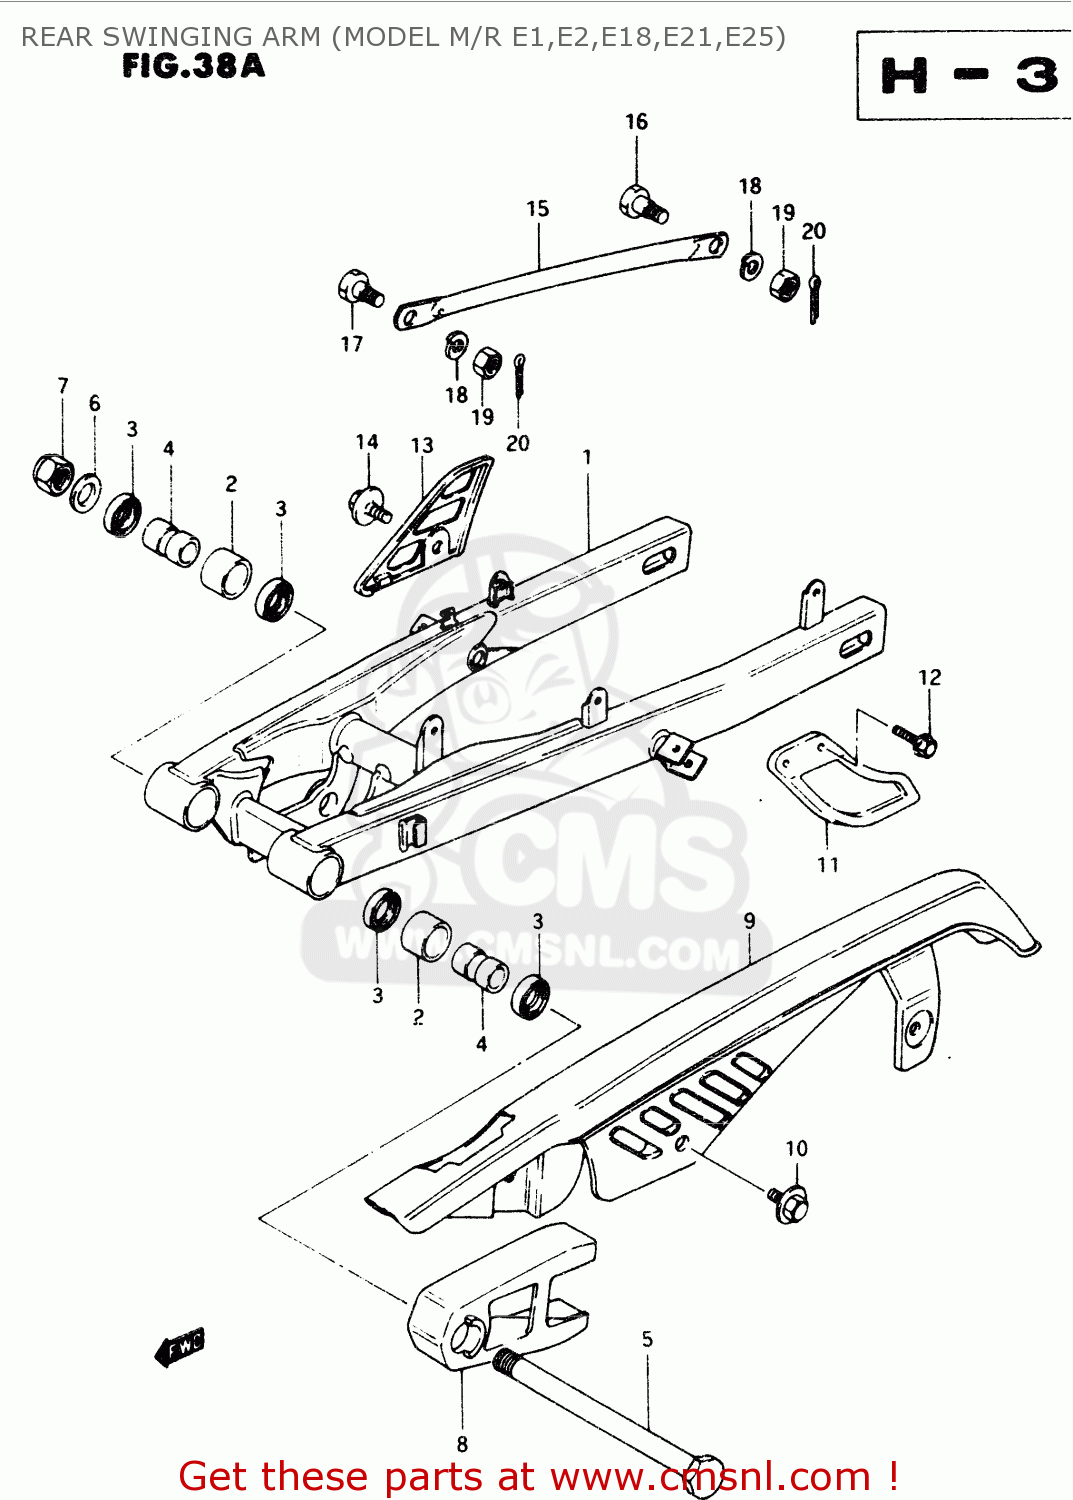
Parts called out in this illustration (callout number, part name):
1	SWINGING ARM ASSY, REAR (SILVER)
2	BUSHING,RR SWGARM PIVOT
3	OIL SEAL
4	SPACER,RR SWINGING ARM PIVOT
5	SHAFT,RR
6	WASHER
7	NUT 14MM
8	BUFFER,CHAIN TOUCH DEFENCE
9	CASE,CHAIN
10	BOLT(6X10)
11	GUIDE,CHAIN
12	BOLT
13	GUARD, FOOT (BLACK)
14	BOLT(6X10)
15	TORQUE LINK,RR
16	BOLT(8X26.5)
17	BOLT(8X22)
18	LOCK WASHER
19	NUT
20	PIN 20X20
